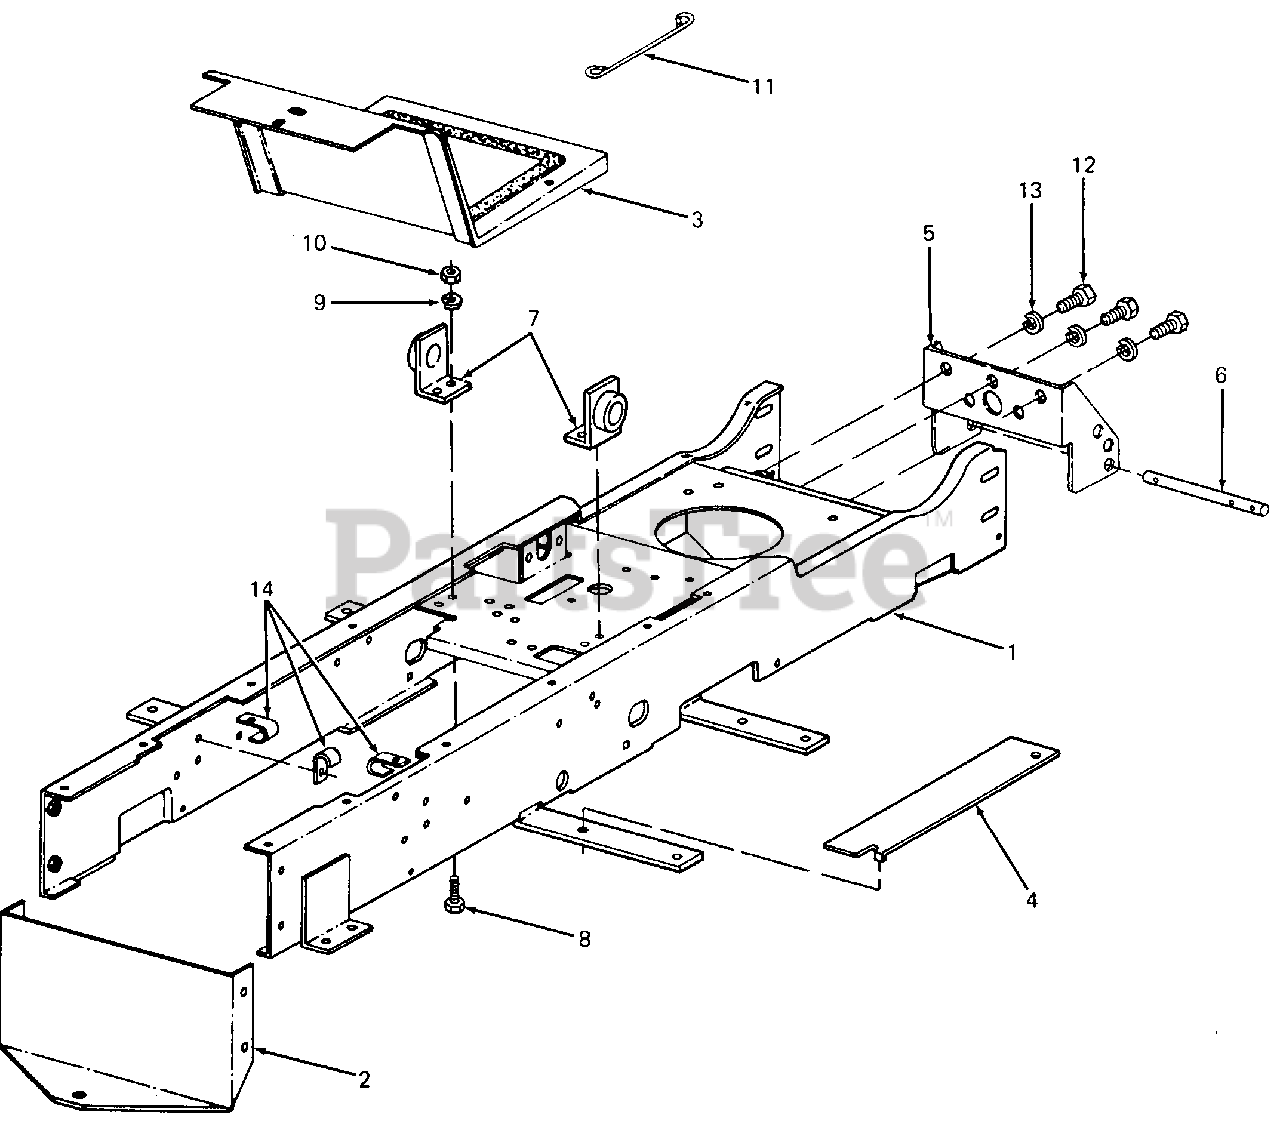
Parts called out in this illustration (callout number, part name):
3	Cover w/Graphic
4	Guard, Fender
5	Bracket, Front Deck
6	Rod, Deck Support
7	Bracket, Lift Shaft
8	Screw, Hex Cap, 5/16-18 X .75 Lg GR5
9	Washer, Lock, 5/16
10	Nut, Hex, 5/16-18 GR5
11	Rod, Link Retaining
12	Screw, Hex Cap, 3/8-16 X .75 Lg GR5
13	Washer, Lock, 3/8
14	Clip, Cable
